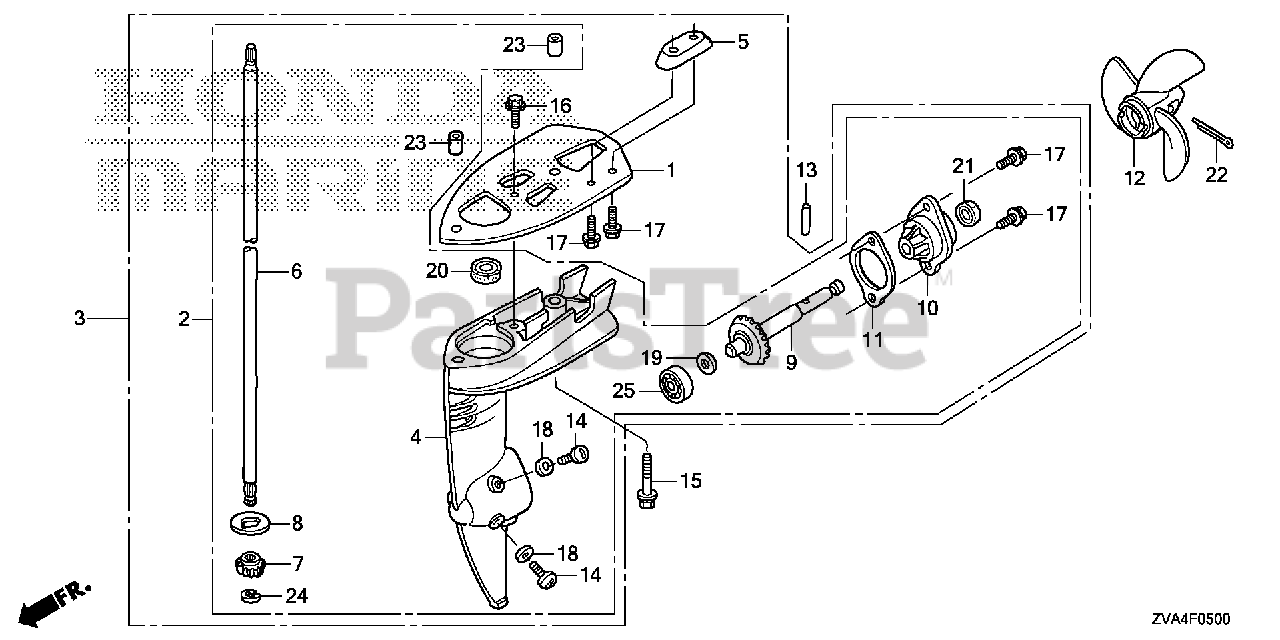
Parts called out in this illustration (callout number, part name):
1	PLATE, CAVITATION *NH246* (LOOSY GRAY)
3	CASE ASSY., GEAR *NH246* (L) (LOOSY GRAY)
4	CASE, GEAR *NH246* (LOOSY GRAY)
5	METAL, ANODE
6	SHAFT, VERTICAL (L)
7	GEAR, PINION
8	WASHER, PINION THRUST
9	SHAFT, PROPELLER
10	HOLDER ASSY., PROPELLER SHAFT *NH246* (LOOSY GRAY)
11	GASKET, PROPELLER SHAFT HOLDER
12	PROPELLER, THREE-BLADE *NH283* (STIN GRAY)
13	PIN, SHEAR
14	BOLT, OIL CHECK
15	BOLT-WASHER (6X35)
16	BOLT, FLANGE (6X12)
17	BOLT, FLANGE (6X16)
18	WASHER, NYLON (8MM)
19	WASHER, GEAR
20	SEAL, WATER (22X21X8)
21	SEAL, WATER (11X21X8)
22	PIN, SPLIT (3.0)
23	PIN A, DOWEL (8X14)
24	E-RING (6MM)
25	BEARING, RADIAL BALL (6000)
